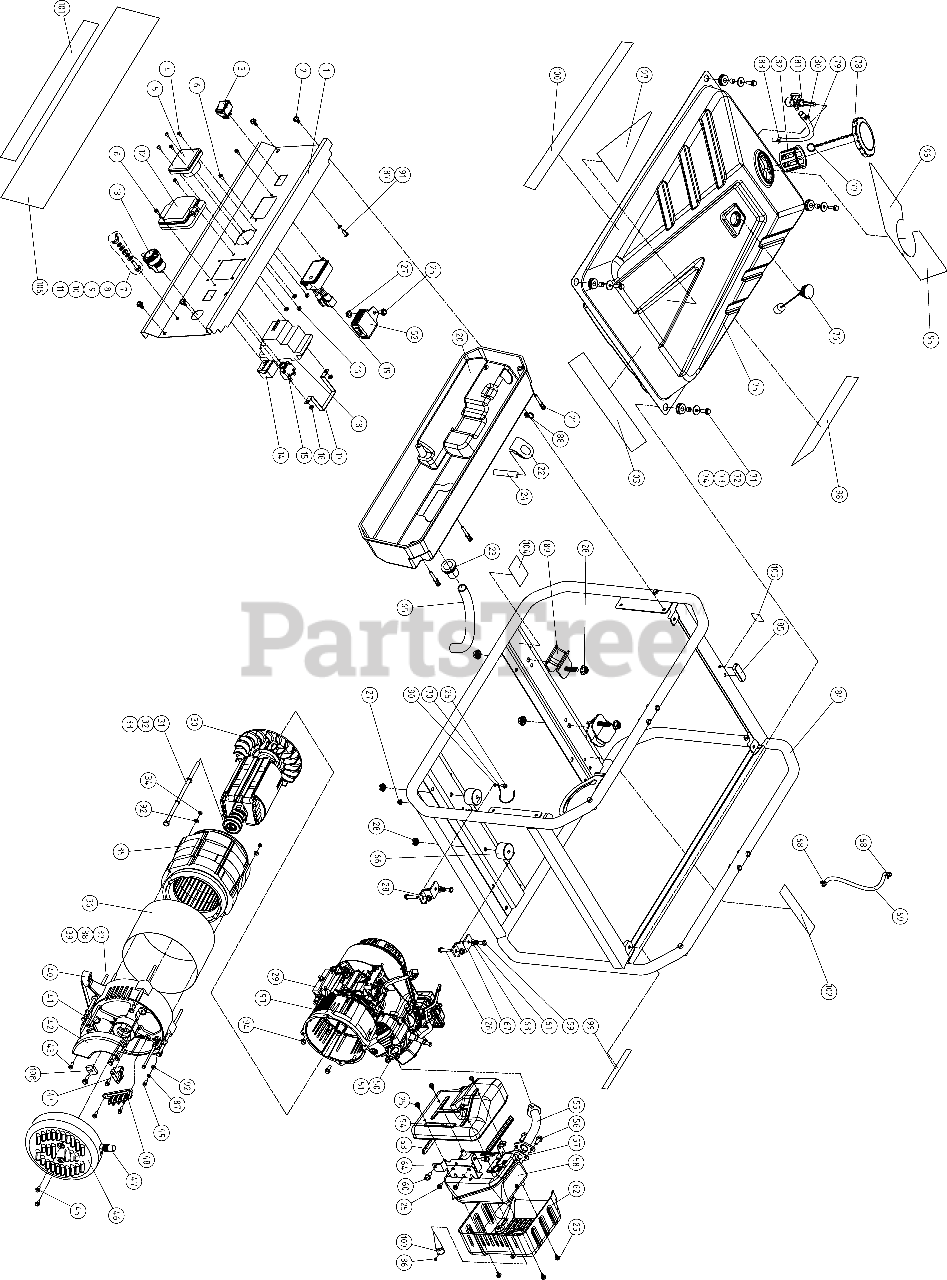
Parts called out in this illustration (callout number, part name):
1	PANEL
2	SCREW, BOLT GB5789-M6X12
4	Screw M4x10
5	Socket 15A/250V
6	SCREW M4X12
8	SCREW, BOLT M6X25
10	WASHER, PLATE GASKET 6
11	WASHER, SPRING GASKET 6
12	Socket Cover(RCD)
13	USB socket
14	DC socket
15	BREAKER, CIRCUIT 10A
16	Nut M4
17	RCD clamp
18	Circuit Breaker
19	Digital Display Meter 240V/50Hz
20	BOX, PANEL
21	SCREW M5X45
22	WIRE SHEATH
23	GROMMET, POWER CORD SHEATH
24	Braided Sleeve 1
25	SCREW, BOLT M6X12
26	BOLT M8X40 GB 5789
29	Engine CH270
30	ROTOR ASSEMBLY
31	BOLT 5/16-24X231 MM
33	WASHER, SPRING
35	Stator Assembly
36	STATOR PROTECTOR
37	WASHER, SPECIAL SPRING 6
38	WASHER, PLATE GASKET 6
39	SCREW BOLT M6X180
40	CAP, BACK COVER
41	BOLT M5X715
42	RECTIFIER AVR (PRO5.5E)
43	SCREW, BOLT GB 5787-M5X16
44	BRUSH, CARBON ASSEMBLY
45	SCREW, BOLT M5X10
46	FAN COVER
47	SLEEVE, MOTOR RUBBER SHEATH
48	BOARD ASSEMBLY, PATCH
49	BOLT GB/T 5783-M5X10
52	USB charging rectifier
53	RUBBER GASKET
54	MUFFLER BACK COVER
55	MUFFLER PIPE WELDING ASSEMBLY
56	SCREW, BOLT M8X22
58	MUFFLER WELDING ASSEMBLY
59	BOLT M8X16
60	SCREW, BOLT M8X16
61	WASHER, SPRING 8
62	MUFFLER FRONT COVER
63	WASHER, FLAT GASKET 8
64	MUFFLER BRACKET PRO 3.7
65	PIPE, CORRUGATED
66	RUBBER FOOT
67	ADAPTER BRACKET
68	CLAMP, FUEL PIPE 5
69	FUEL LINE
70	GROUND WIRE
71	SCREW, BOLT GB 5787-M6X20
72	MOUNT, FLAT GASKET GB/T 5287-6
73	SPACER, INNER RING
74	SPACER, FUEL TANK BUSHING
75	TANK ASSEMBLY (PRO3.7E)
76	FUEL LEVEL GAUGE ASSEMBLY
77	RETAINER, TANK CAP PULL RING
78	CAP ASSEMBLY - FUEL TANK (EPA)
79	FUEL LINE
80	CLAMP, FUEL LINE 6
81	VALVE,FUEL SHUT OFF
82	FILTER , FUEL TANK
83	CLAMP, FUEL LINE 1 USE 14 237 01-S
84	Frame assembly
85	DAMPER, HANDLE DAMPING PAD
87	WASHER, SPRING GB 93-5
88	STRAP, CABLE TIES 3.2X120 (WHITE)
89	VIBRATION ABSORBER
90	GROOVED METAL GASKET 6
91	SCREW M5X12
92	WASHER, PLATE GT/T 95
93	FRONT COVER
94	BOLT 5/16-24 27MM
95	LOGO LABEL (RESERVOIR PORT)
96	Warning Label (Reservoir Port Right)
97	Runing Watts Label(Fuel Tank)
98	Left Logo Label (Fuel Tank)
99	SAFETY DECAL
100	CPSC DECAL_5.2
101	QUICK START LABEL
102	Data Label
103	DECAL, GENERATOR_WARNING
105	FUEL SWITCH DECAL
107	SPARK ARRESTER
108	RETAINER, 12V DC CHARGE BRIDGE
